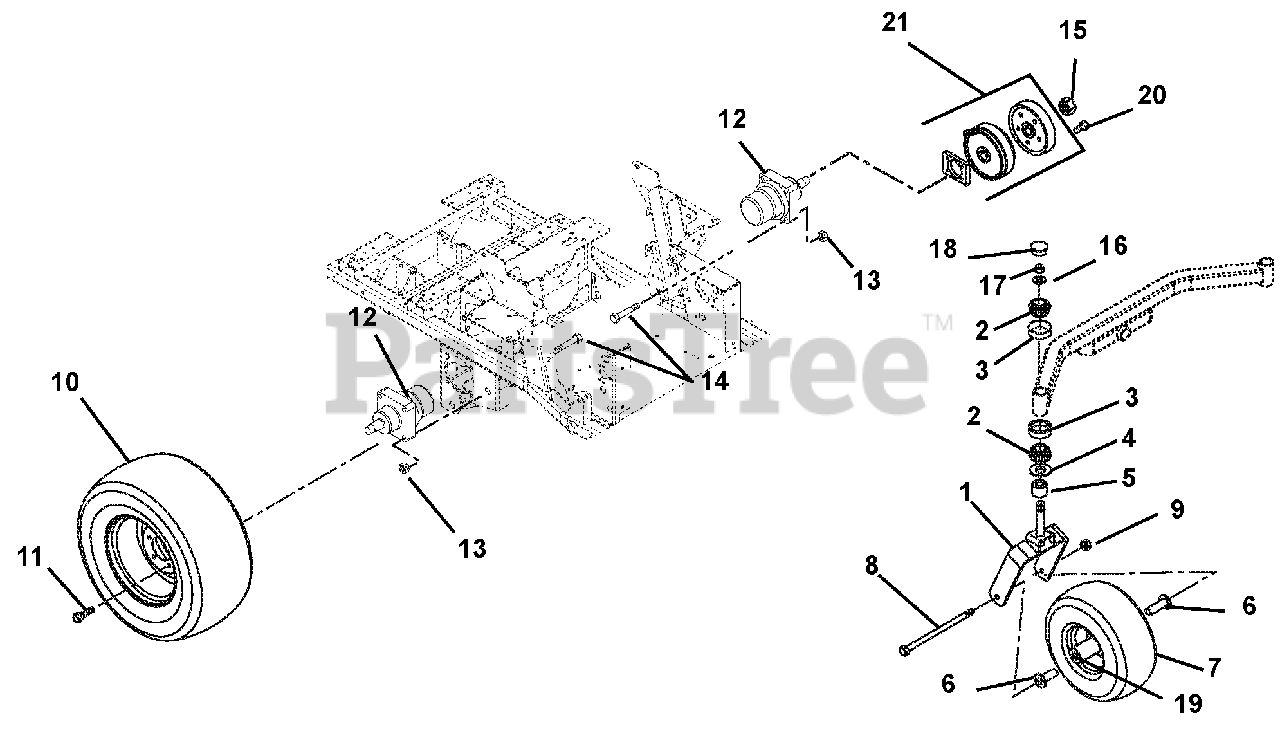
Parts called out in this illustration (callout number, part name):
1	FORK - FRONT
2	BRG, CONE W/ GREASE
3	BRG-CUP1.980X.420
4	BEARING SEAL 1.5 X 2 X .18
5	SPACER 1.005X1.5075X.375
6	SPACER, FRONT WHEEL
7	TIRE/WHEEL ASSY 15X6-6
8	@BLT-HEX .50-13X9.00 GR5 YWZC
9	@NUT-LK-CTR .50-13 YWZC
10	TIRE/WHEEL ASSY 24X12-12
11	BLT, LUG .50-20 X 1.38
12	MOTOR, PARKER WHEEL
13	@NUT-LK-TOP-FLG .50-13 YWZC
14	BOLT, WHEEL MOTOR 1/2-13X2.75
15	NUT-LK-JAM-PTCH 1.00-20
16	@WSHR-FL-STL.812X1.50X.135YWZC
17	NUT-JAM CTRLK .75-16 YWZC
18	CAP,DUST
19	BRG, 25MM ID X 52MM OD X 15MM
20	@BLT-HEX .31-18X1.50 GR5 YWZC
21	KIT, BRAKE SERVICE (1-SIDE)
